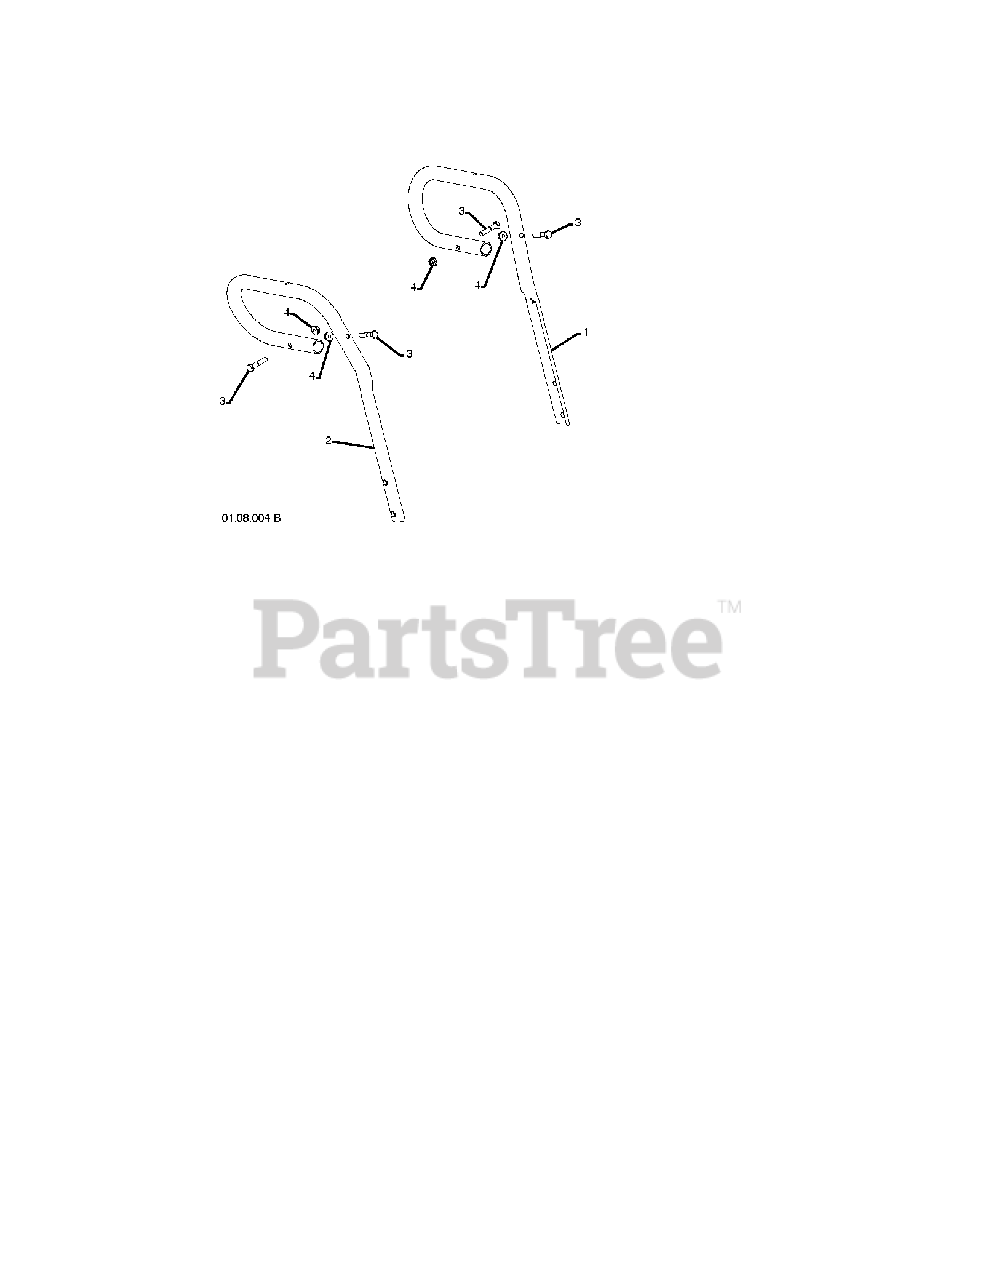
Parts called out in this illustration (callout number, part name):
2	TUBE.HANDLE.LOOP.RH.BLACK
3	HEX BOLT
4	NUT, LOCK 5/16-18
